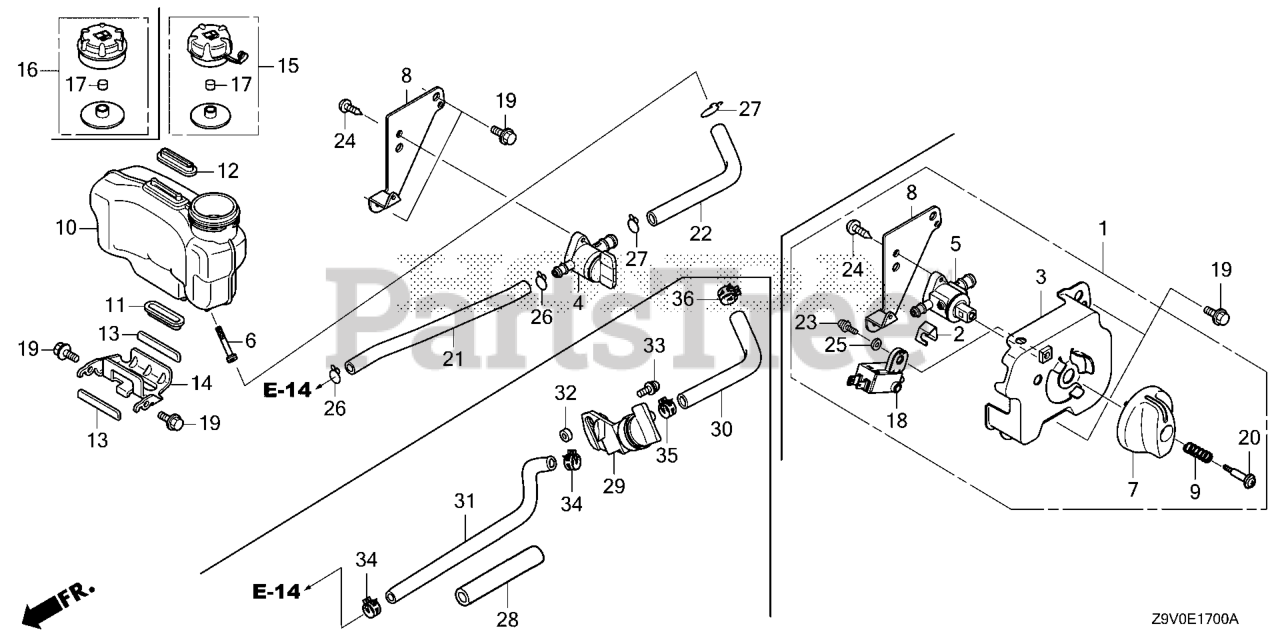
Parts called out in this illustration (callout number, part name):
4	PETCOCK ASSY.
6	FILTER, FUEL
8	STAY, PETCOCK
10	TANK, FUEL
11	RUBBER A, TANK MOUNTING
12	RUBBER A, TANK MOUNTING
13	RUBBER B, TANK MOUNTING
14	STAY, FUEL TANK
15	CAP ASSY., FUEL TANK
17	SPONGE, FUEL CAP BREATHER
19	BOLT, FLANGE (6X14)
21	TUBE, FUEL (4.5X110)
22	TUBE, FUEL (7.3X160)
24	SCREW, TAPPING (5X12) (PO)
26	CLIP, TUBE (C9)
27	CLIP, TUBE (B12.5)
